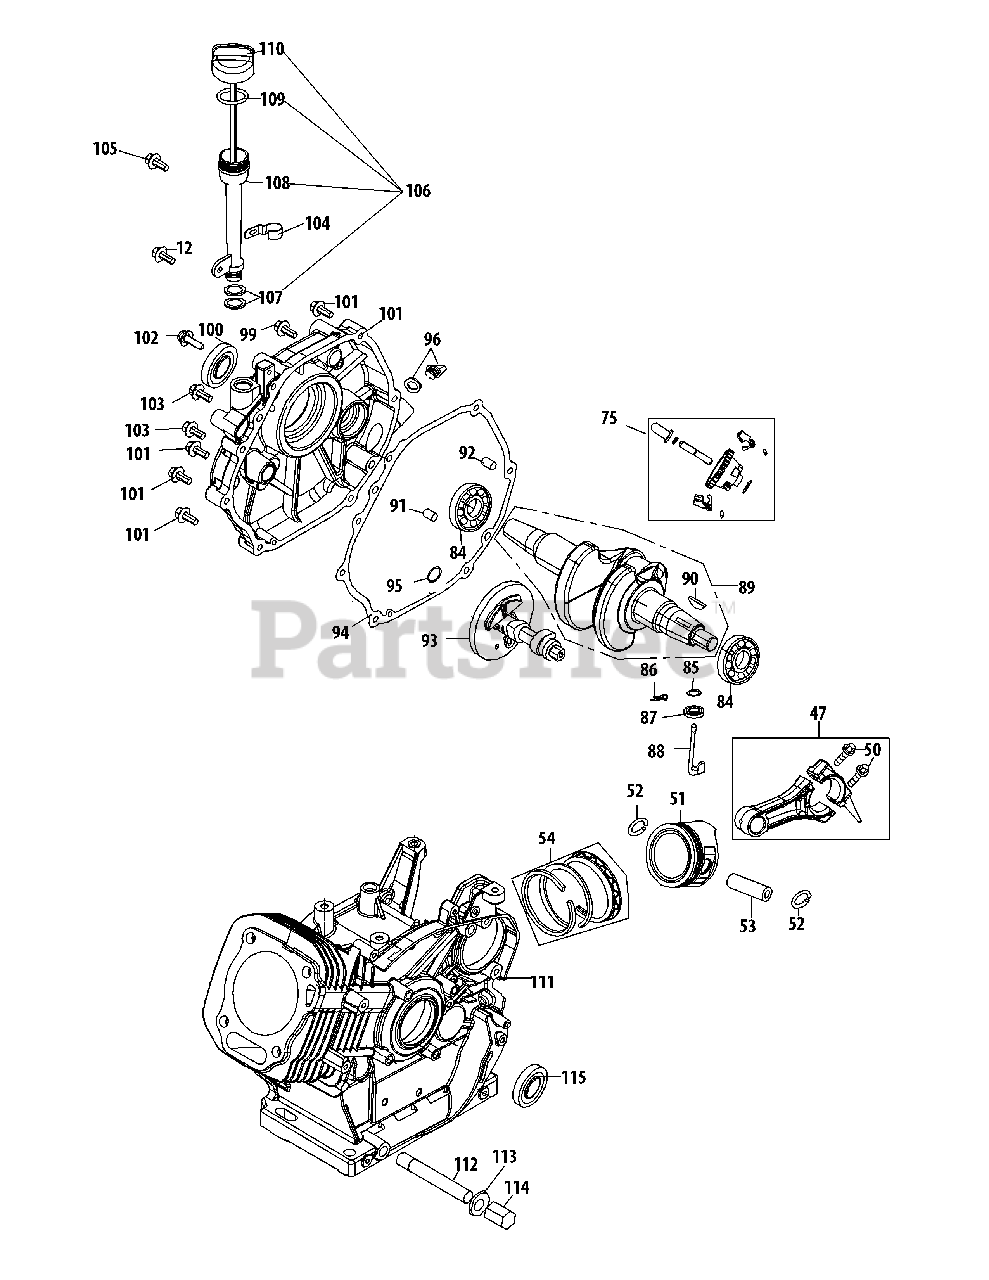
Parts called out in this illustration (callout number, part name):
47	CONNECTING ROD ASSEMBLY
50	CONNECTING ROD BOLT
51	PISTON
52	PISTON PIN SNAP RING
53	PISTON PIN
54	PISTON RING SET
75	GOVERNOR GEAR
84	RADIAL BALL BEARING
85	WASHER 8×20×0.8
86	COTTER PIN
87	GOVERNOR SEAL
88	GOVERNOR ARM SHAFT
89	CRANKSHAFT ASSEMBLY
90	WOODRUFF KEY
91	DOWEL PIN 9×12
92	DOWEL PIN 7×14
93	CAMSHAFT ASSEMBLY
94	CRANKCASE COVER GASKET
95	WASHER 16×24×0.5
96	DIPSTICK ASSEMBLY
99	CRANKCASE COVER
100	OIL SEAL, 30×46×8
101	BOLT M8×38
102	BOLT M8×45
103	BOLT M8×35
104	DIPSTICK CLAMP
105	BOLT M6×8
106	DIPSTICK ASSEMBLY
107	OIL FILL TUBE O-RING
108	OIL FILL TUBE
109	DIPSTICK O-RING
110	DIPSTICK
111	CRANKCASE COMP.
112	OIL DRAIN PIPE
113	WASHER 10×16×1.5
114	OIL DRAIN PLUG
115	OIL SEAL 30×46×8
